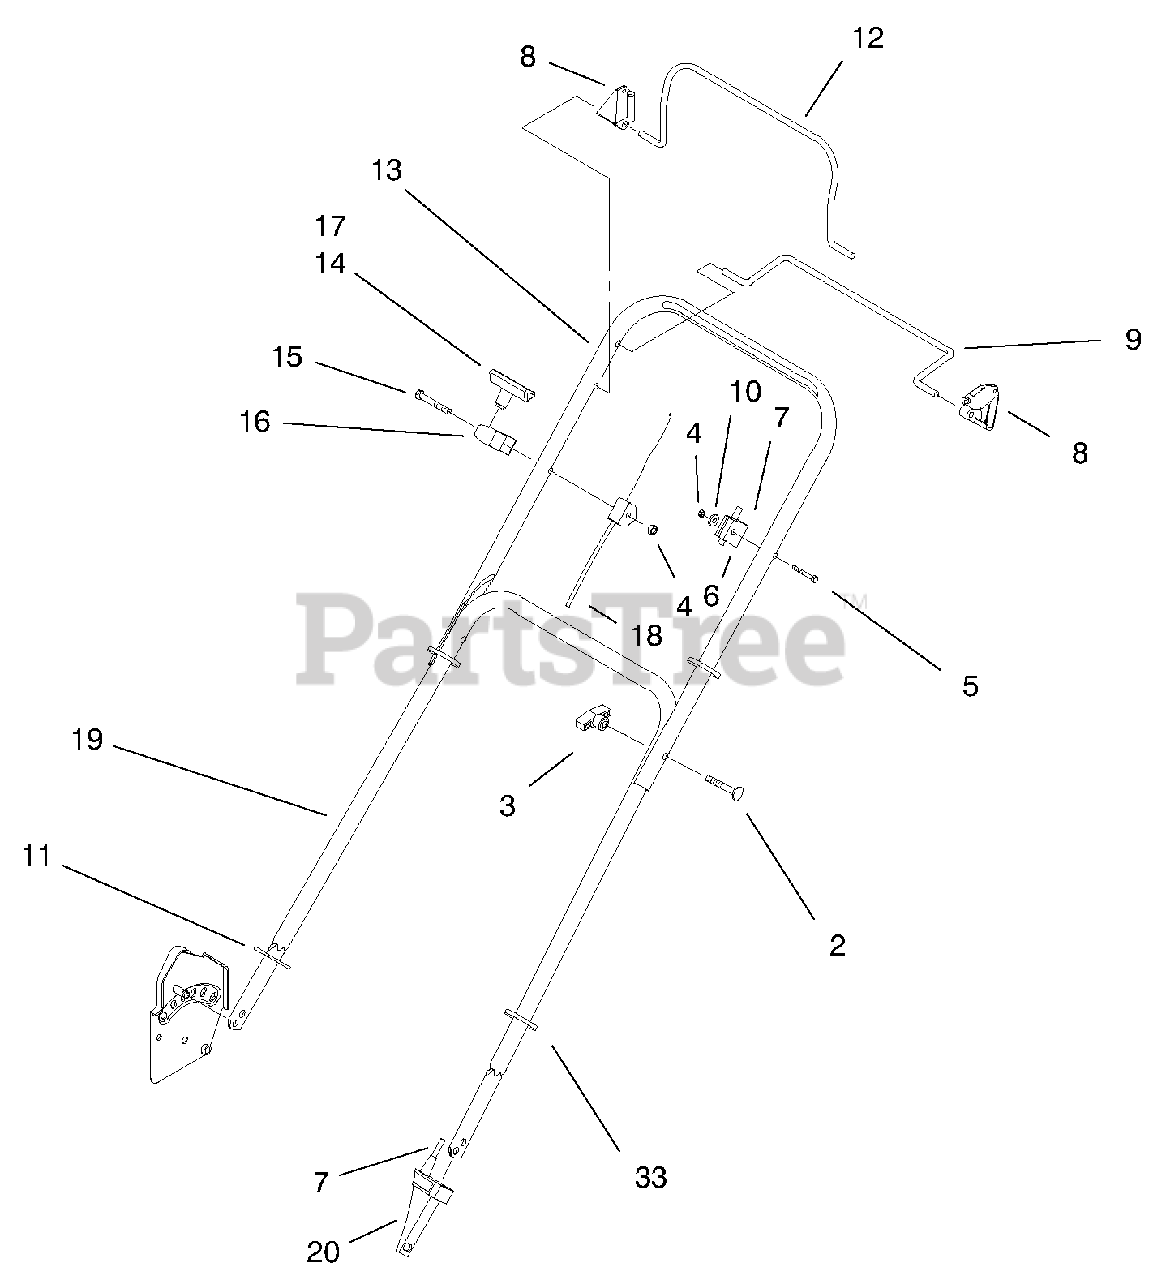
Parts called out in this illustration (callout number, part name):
2	Screw-Handle
4	Nut-Lock
5	Screw-Handle
6	Anchor-Cable
7	Cable-Traction
8	Stop-Pivot
9	Bail-Sp Control
10	Washer-Flat
11	Handle-Guard
12	Bail-Flywheel Brake
13	Handle Section-Upper
14	Handle-Starter
16	Guide-Rope
17	Staple-Handle
18	ASM-Brake Cable
19	Handle Section-Lower
20	Anchor-Cable
33	Tie Strap
